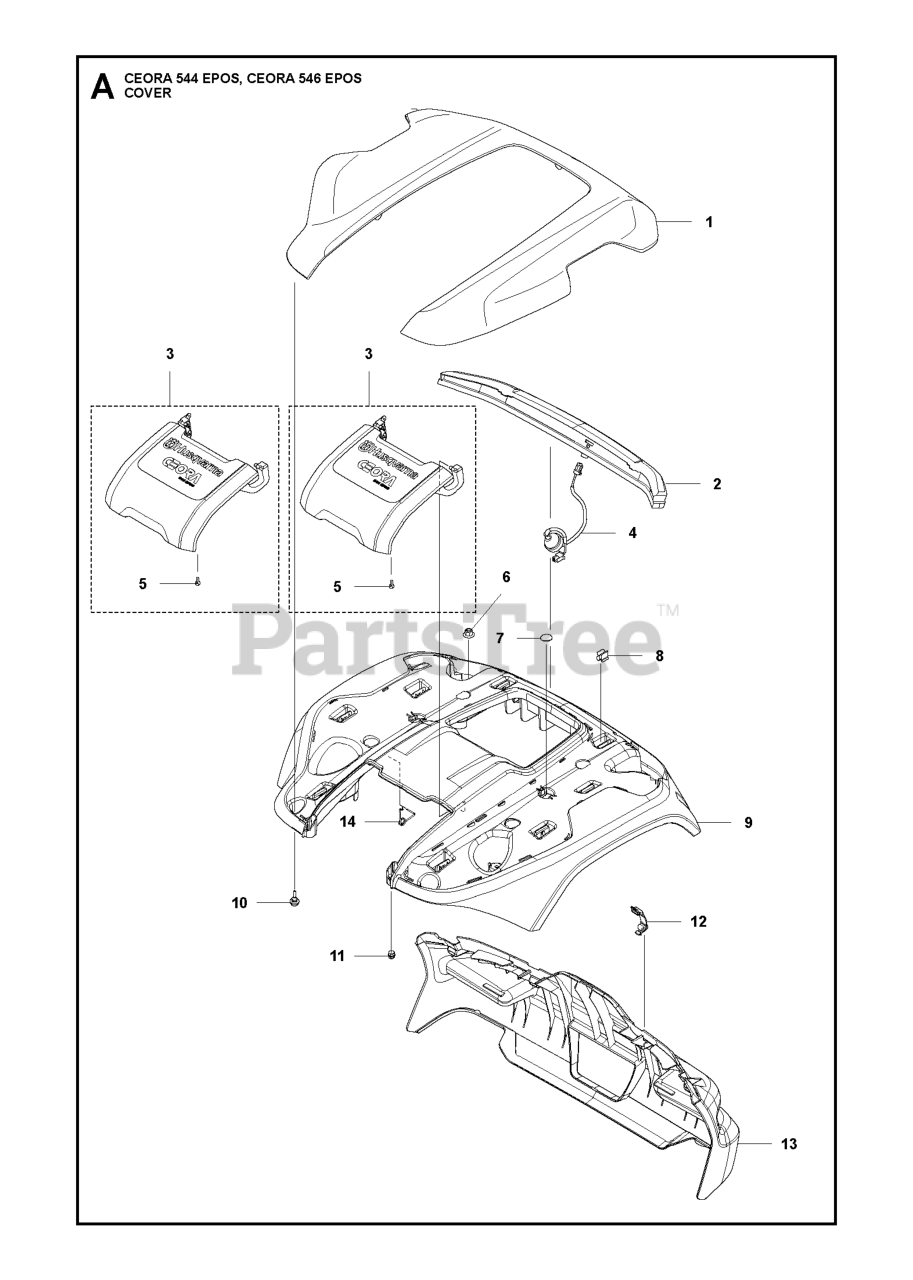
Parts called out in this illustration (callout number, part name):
1	COVER TOP ORANGE
2	WIRING ASSY LED-LIGHT REAR
3	HATCH KIT CEORA 546
3	HATCH KIT CEORA 544
4	WIRING ASSY LED LIGHT 3P REAR
5	SCREW
6	NUT FLANGE
7	MAGNET D20X2
8	Clips
9	BODY
10	BUFFER
11	MAGNET
12	SNAP LOCKING GREY. ONLY USE F
13	BUMPER
14	SPRING
